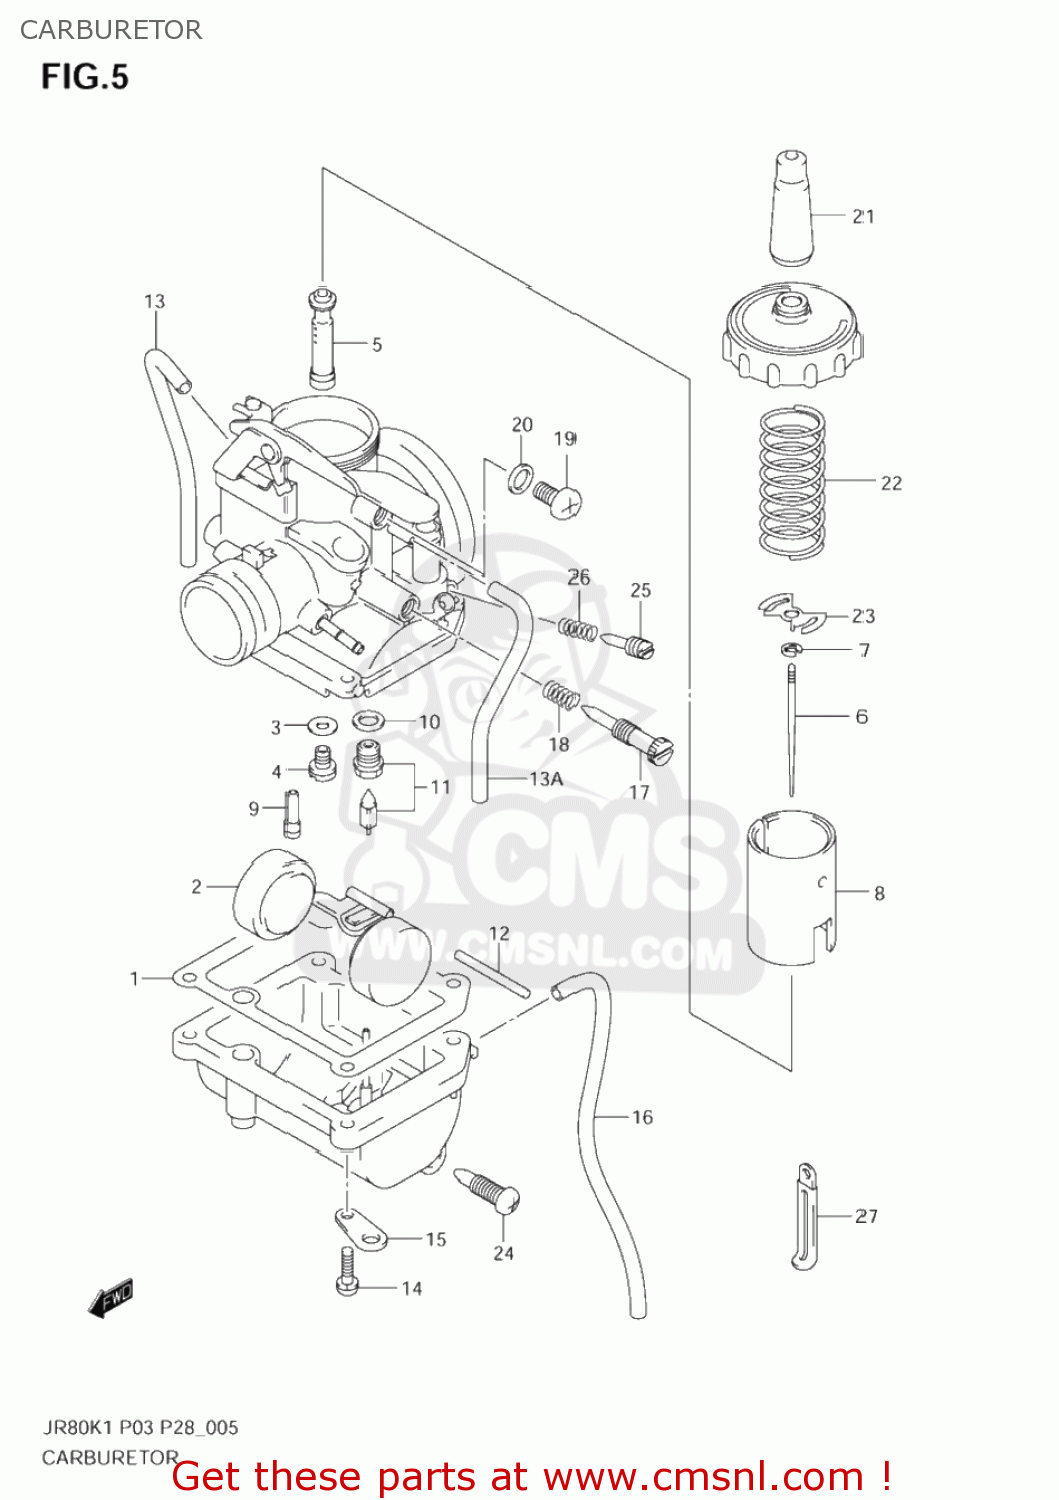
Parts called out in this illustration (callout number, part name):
1	CARBURETOR ASSY
1A	GASKET,FLOAT CAHMBER (NAS)
2	FLOAT
3	WASHER
4	JET,MAIN(87.5)
5	JET,NEEDLE
6	NEEDLE,JET
7	E RING
8	VALVE,THROTTLE
9	JET,PILOT(25)
10	GASKET,NEEDLE VALVE (NAS)
11	VALVE ASSY,NEEDLE
12	PIN,FLOAT
13	HOSE(3X5X600)
13A	HOSE(3X5X600)
14	SCREW
15	PLATE
16	HOSE(3X5X125)
17	SCREW,THROTTLE STOP
18	SPRING,THROTTLE SCREW
19	SCREW
20	GASKET,DRAIN PLUG (NAS)
21	CAP,CABLE ADJUSTER
22	SPRING,THROTTLE VALVE
23	STOPPER,NEEDLE CLIP
24	PLUG,DRAIN
25	SCREW,PILOT AIR
26	SPRING
27	CLAMP(L:80)
